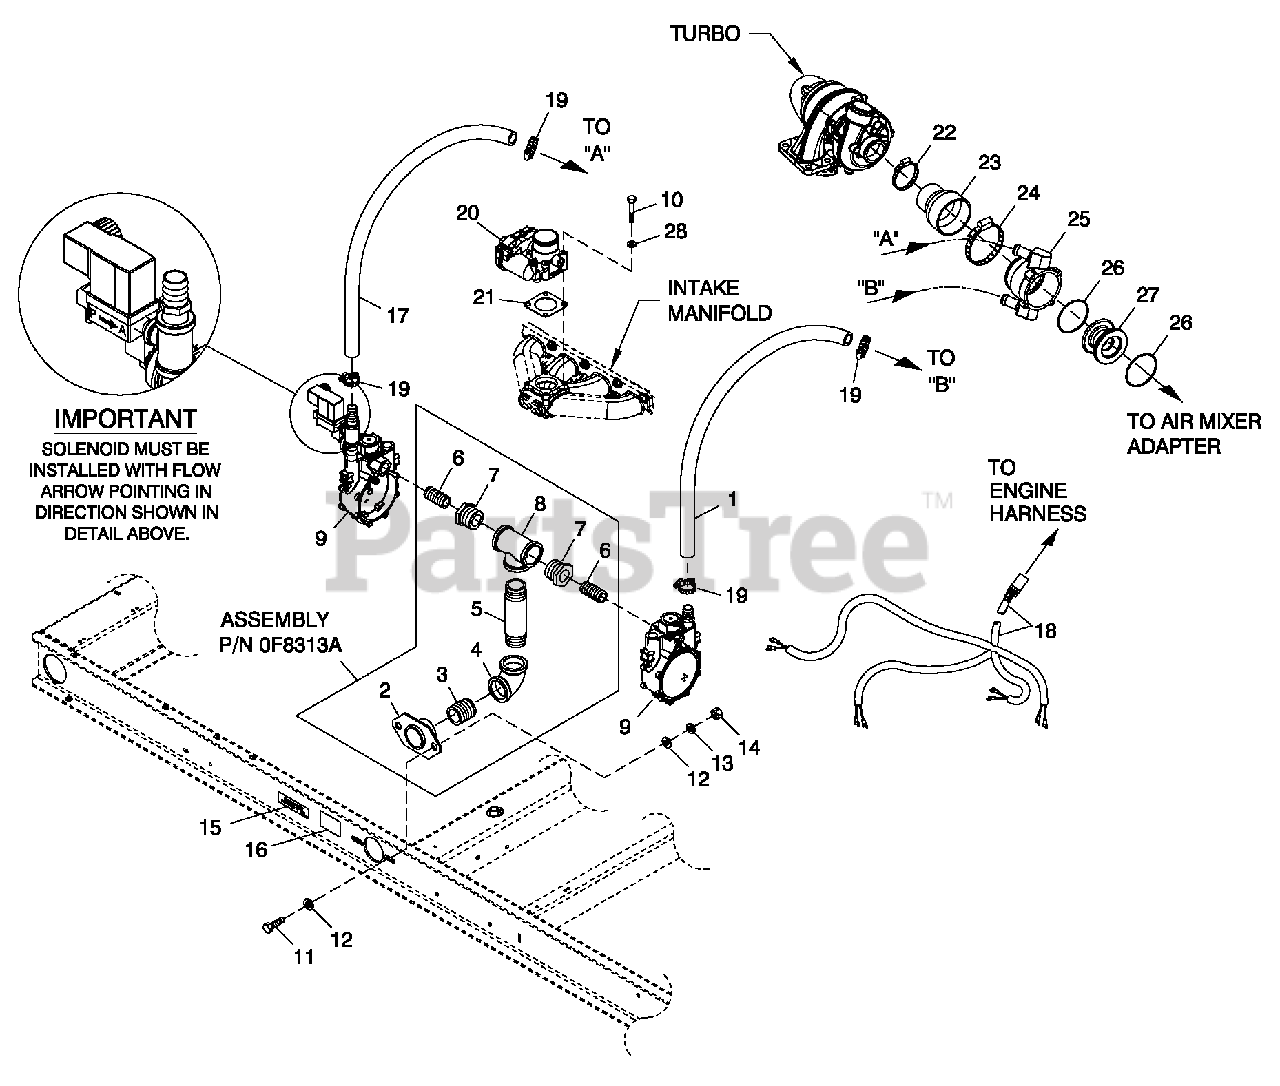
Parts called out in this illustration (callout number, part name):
1	HOSE 3/4 ID SAE-30R2 (43" LG)
2	FLANGE FUEL INLET
3	NIPPLE CLOSE 1.25 NPTX 1.625
4	ELBOW 90D 1-1/4 NPT
5	NIPPLE PIPE 1.25 NPT X 5.5 BLIRN
6	NIPPLE CLOSE 3/4X1.375
7	BSHG RDCR HEX1-1/4-3/4
8	PIPE TEE 1-1/4 NPT
9	REG ASSY 2.4L 60KW NG CPL
10	SCREW SH C M6-1.0 X 45 C12.9
11	SCREW HH CM8-1.25X25 C8.8
12	WASHER FLAT 3/8-M10 ZINC
13	WASHER LO CK M8-5/16
14	NUT HEX M8-1.25 G8 CLEAR ZIN C
15	DE CAL FUEL INLET NG
16	DE CAL INLET PRESSURE
17	HOSE 3/4 ID SAE-30R2 (43" LG)
18	HARNESS FUEL JUMPER DUAL REG
19	CLAMP HOSE #10 .56-1.06
20	ACTUATOR BOS CH 40 GOVERNOR
21	GASKET BOS CH 32
22	CLAMP HI TORQUE 1.75-2.625
23	REDU CER RUBBER 3.0"-2.00"
24	CLAMP HI TORQUE 2.75 - 3.625
25	MIXER 40/60MM A CTUATOR ASSY
26	O-RING 2-3/4X3/32X2-15/16
27	VENTURI THROTTLE 32MM
28	WASHER LO CK M6-1/4
